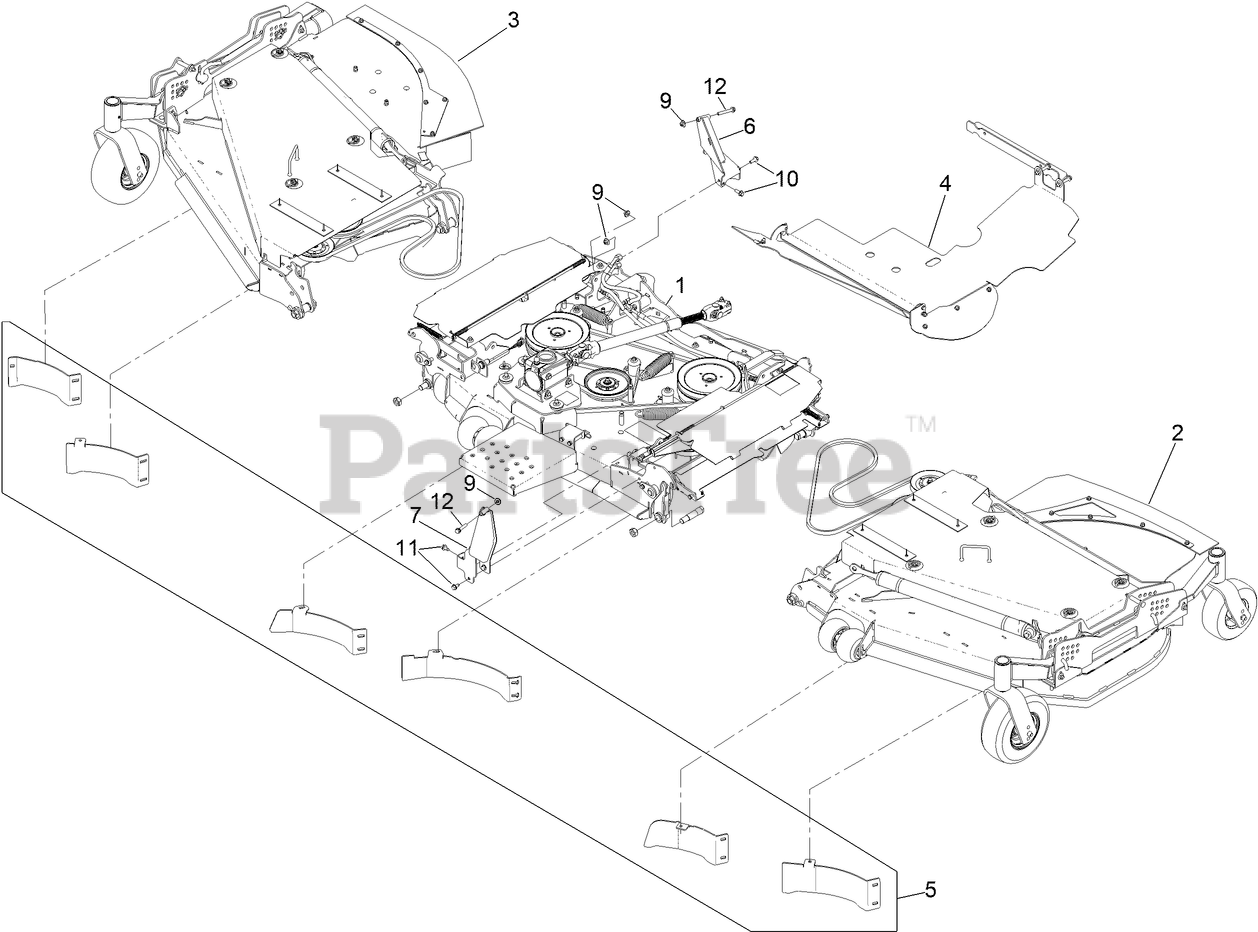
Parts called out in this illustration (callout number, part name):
1	ASM-DECK, CTR
2	ASM-DECK, LH WING
3	ASM-DECK, RH WING
4	DISCHARGE-TUNNEL ASM, 144
5	KIT-FINISH CUT BAFFLE 144
6	WELD-RH SPRING MOUNT-UPSTOP
7	BRACKET, LH CENTERDECK-SPRING [BL
9	NUT-FLANGE, NI
10	SCREW-HHF
11	SCREW-HWH
12	SCREW-HHF
